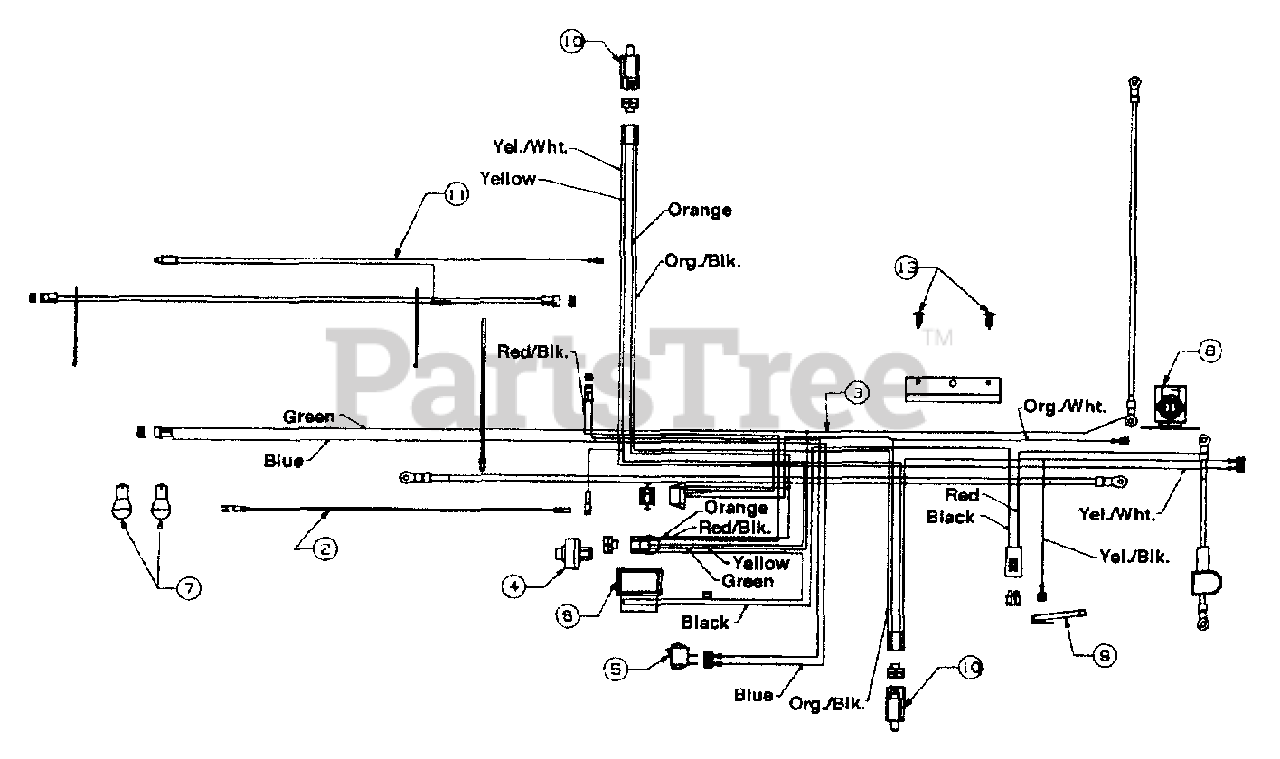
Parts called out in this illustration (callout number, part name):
2	Harness Adapter
3	Wire Harness w/Light Switch & Amp
4	Ignition Switch
5	Light Switch
6	Ammeter
7	Bulb
8	Solenoid
9	Safety Switch (Reverse)
10	Safety Switch
11	Harness Adapter (Alt.)
13	Ratchet
